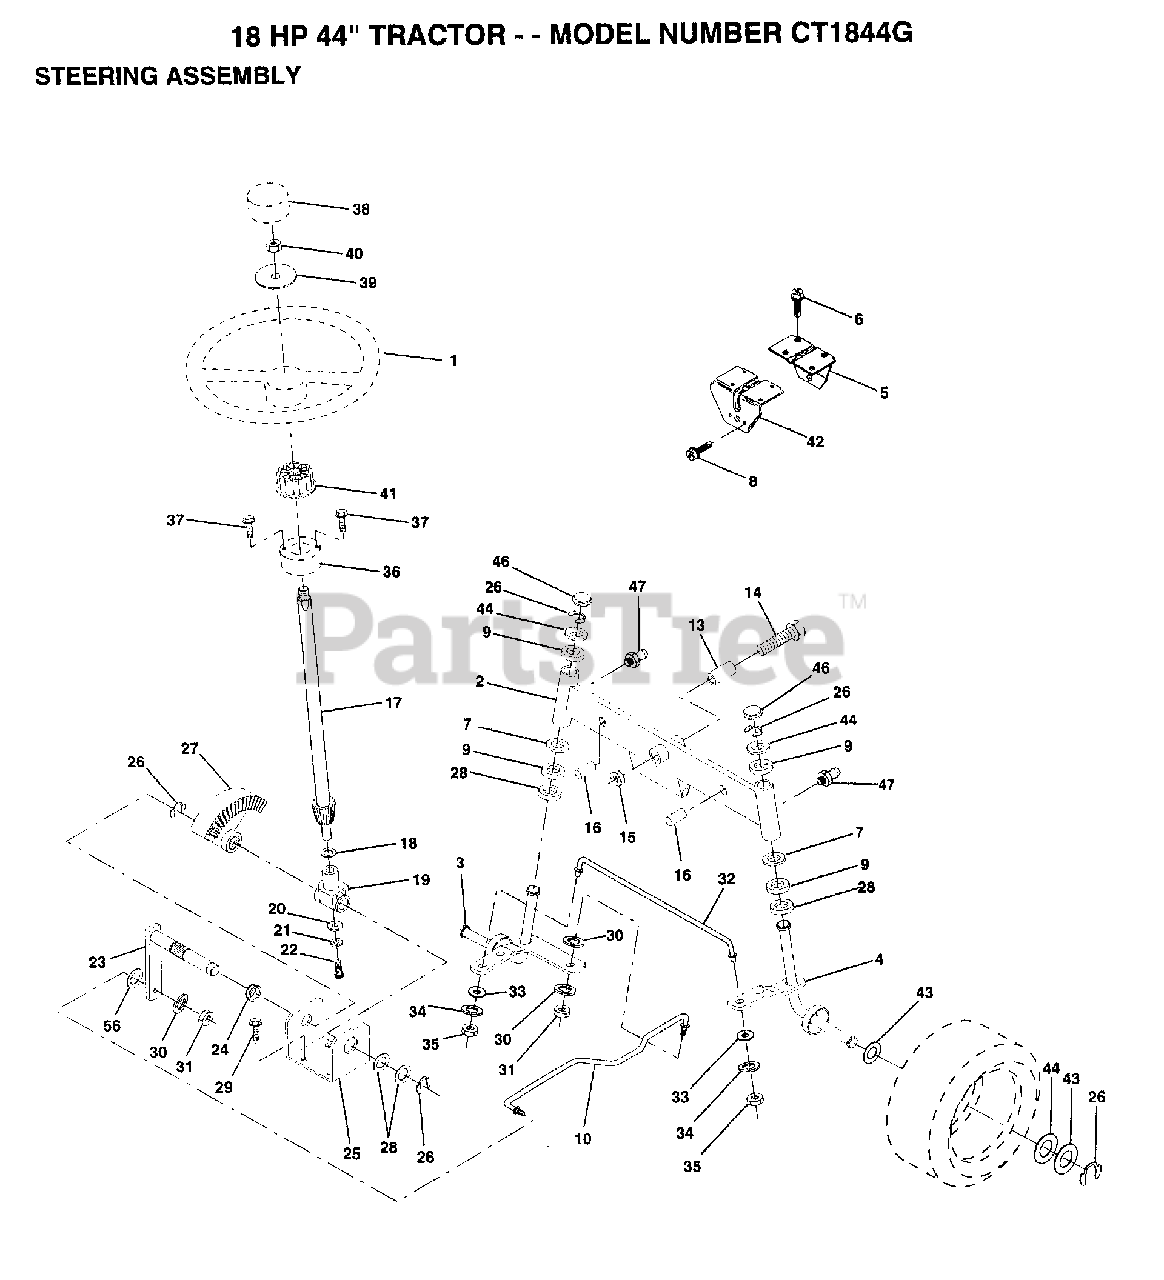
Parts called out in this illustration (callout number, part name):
1	WHEEL STR AYP BLK
2	AXLE ASM FRONT
5	SUPPORT.SADDLE.FT
6	SCREW
7	WASHER, 27/32X1-1/4X 16 GA
8	SCREW LT
9	COL. SRTG. BEAR.
13	BEARING
14	BOLT LT
15	"NUT-LOC,FLANGE LT"
16	AXLE PIN
18	THRUST WASHER
19	SUPPORT.SHAFT
21	LOCKWASHER
22	"SCREW,SPECIAL"
24	NYLINER T
25	"BRKT,STEERING"
26	RING
27	GEAR SECTOR
28	WASHER .T
29	SCREW
30	LOCKWASHER
32	TIE ROD
33	WASHER M
34	LOCKWASHER
35	NUT.LOCK.5/16-24
38	CAP STEER AYP
39	WASHER
41	ADAPTER LT
42	SUPPORT-SADDL T
43	WASHER
44	WASHER
46	CAP
47	ZERK M
56	WASHER
